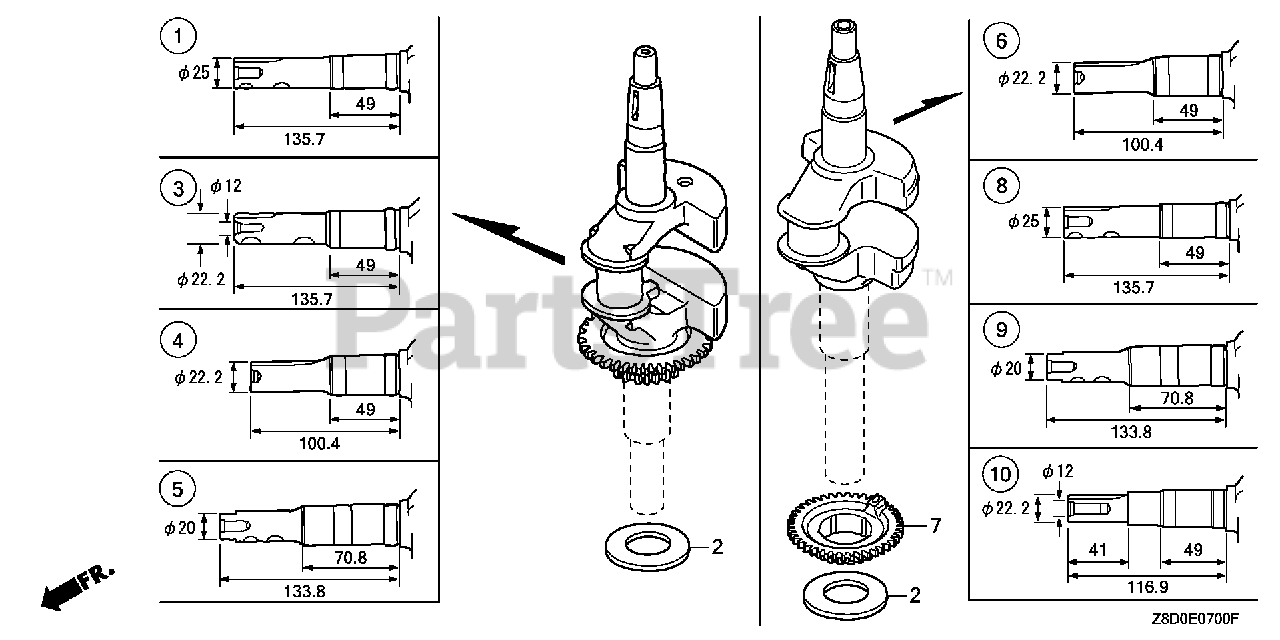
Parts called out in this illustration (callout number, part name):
2	WASHER, THRUST
7	PULLEY, TIMING BELT DRIVE
9	CRANKSHAFT
